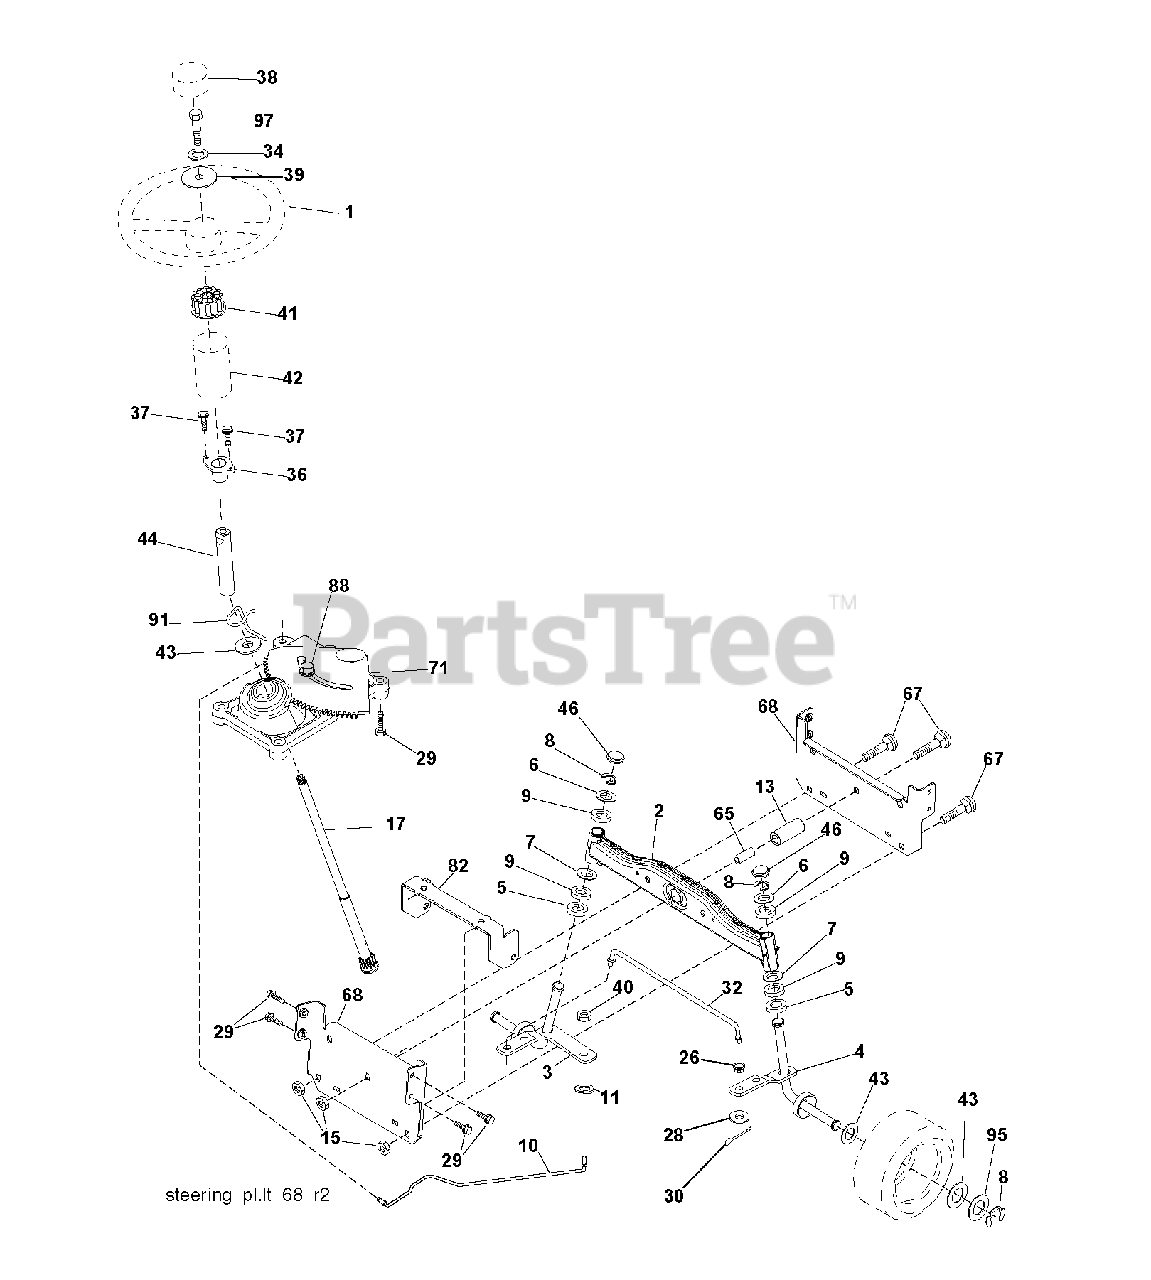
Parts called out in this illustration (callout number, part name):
2	AXLE.HALF.ASM.WELDED
3	SPINDLE.ASM.LH.15"TIRES
4	SPINDLE.ASM.RH.15"TIRES
8	RING CLIP
9	BRNG T
10	DRAGLINK.15".TIRES.2001
11	WASHER, LOCK 3/8
13	TUBE, PIVOT AXLE
15	NUT
17	SHAFT STEERING SPLINE
26	BUSHING.DRAGLINK
28	WASHER
29	SCREW, 3/8-16X3/4
30	COTTER PIN
32	ROD.TIE.WIRE.FORM
34	LOCKWASHER
36	BUSHING, STEERING
39	WASHER.11/32
40	NUT CROWNLOCK 3/8-24
41	ADAPTER, WHEEL STNG..
42	BOOT.STEERING.SHAFT.BLACK
44	SHAFT.EXTEN.STRG.SPLINE
46	CAP.SPINDLE
65	SPACER BRACE AXLE
67	BOLT CARRIAGE
68	BRACE.AXLE.15"TIRES
71	STEERING ASM
82	BRACKET.SUSP.CHASSIS.FRONT.15
88	BOLT, SHOULDER 7/16-20
91	CLIP.STEERING
95	WASHER.HARDENED
